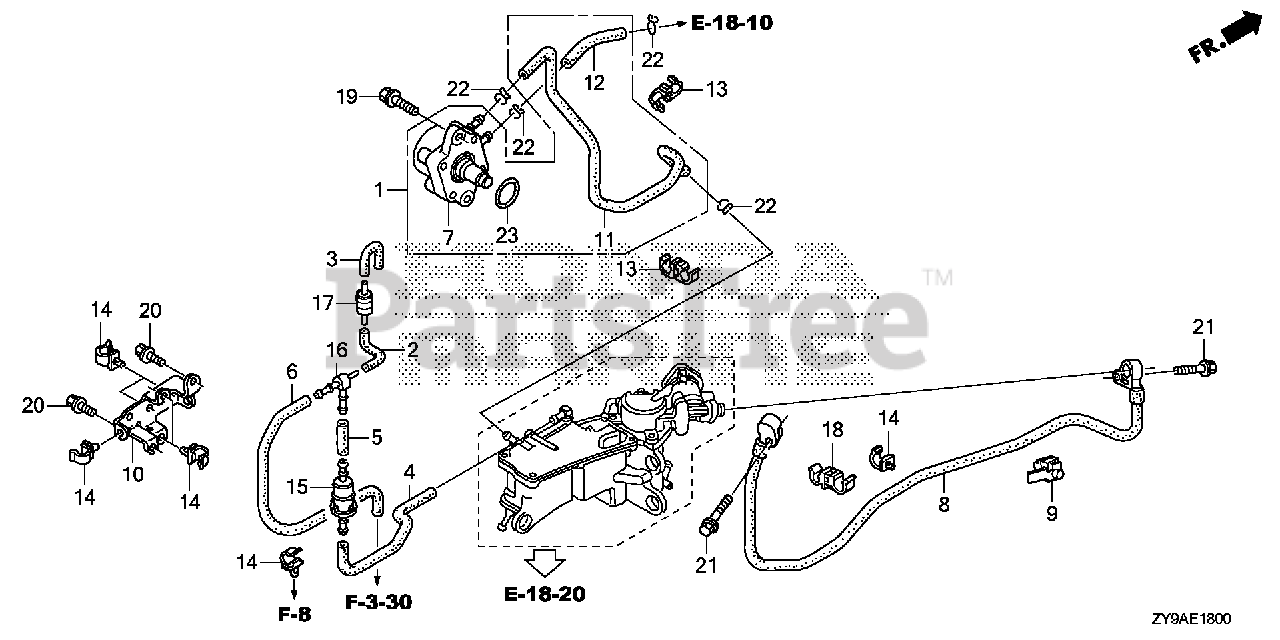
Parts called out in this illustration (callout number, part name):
1	PUMP ASSY. KIT, FUEL (MSDS)
2	TUBE A, CHECK VALVE
3	TUBE B, CHECK VALVE
4	TUBE A, AIR VENT
5	TUBE B, AIR VENT
6	TUBE C, AIR VENT
7	PUMP ASSY., FUEL (MSDS)
8	HOSE, FUEL
9	GROMMET, FUEL HOSE
10	BRACKET, FUEL TUBE CLAMP
11	TUBE D, FUEL
12	TUBE E, FUEL
13	CLAMP A, FUEL TUBE
14	CLAMP B, FUEL TUBE
15	FILTER, FUEL
17	VALVE, CHECK
18	CLAMP, OXYGEN SENSOR
19	BOLT, FLANGE (6X22)
20	BOLT, FLANGE (6X14) (CT200)
21	BOLT, FLANGE (6X25)
22	CLIP, TUBE (B12)
23	O-RING (31.2X2.4)
